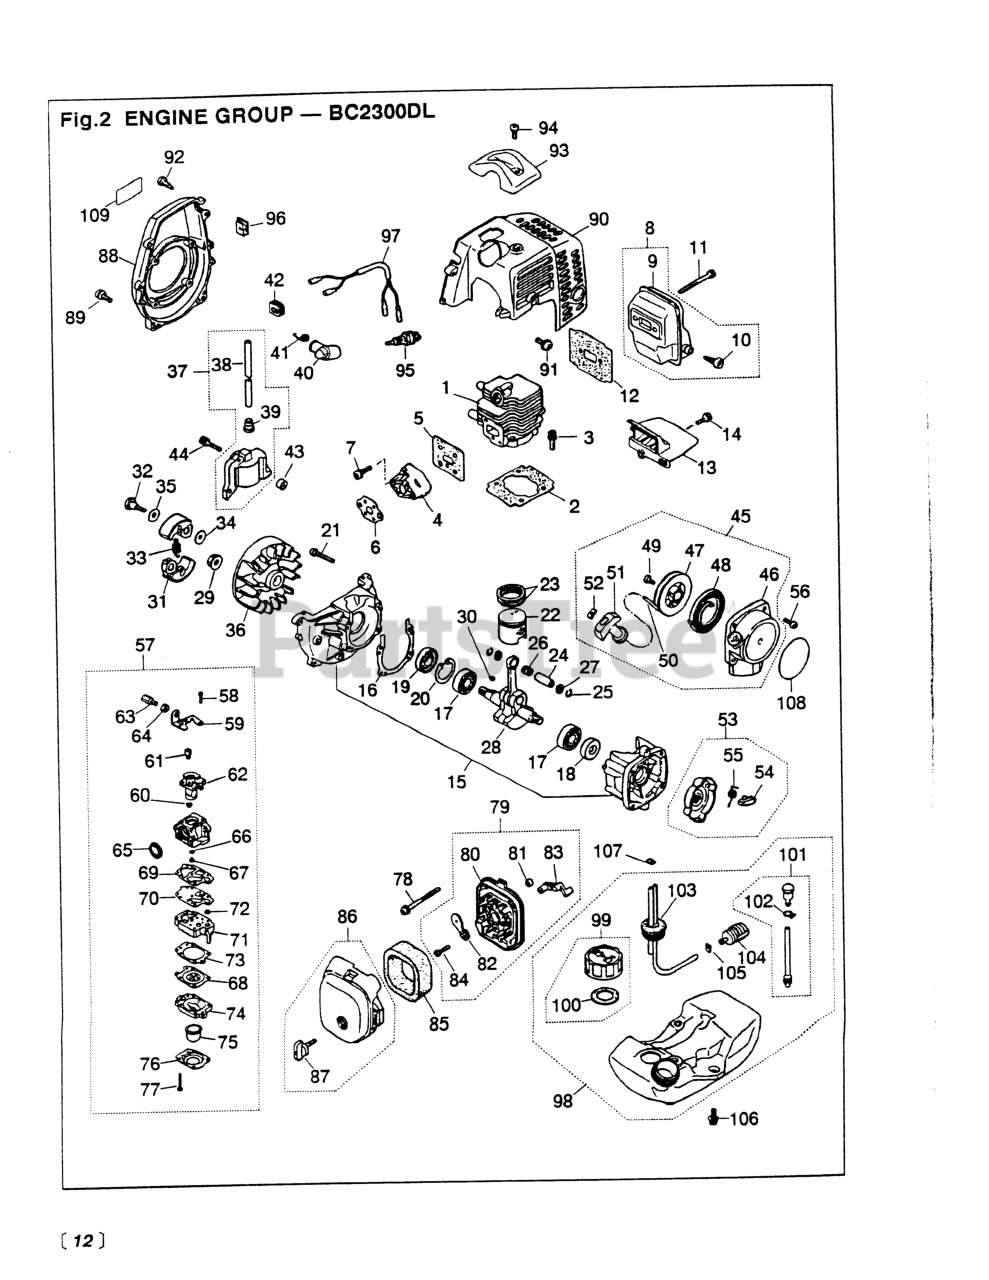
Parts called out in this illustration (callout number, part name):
1	CYLINDER
3	BOLT, M5 X 22
7	SCREW, M5X20 (RPLS.1400-75510)
9	MUFFLER ASSY (USE 5913-15100)
10	ARRESTER (RPLS 5850-15140)
11	BOLT, M5 x 50
12	GASKET, MUFFLER
14	SCREW, M4 X 16
15	CRANKCASE
17	BEARING
18	SEAL, OIL (RPLS 1100-21210)
19	SEAL, OIL (RPLS 1140-21220)
20	RING, SNAP, M28 x 1.2
21	SCREW, M5 x 30(RPLS 0263-00530
24	PIN, PISTON 5x8x26
25	RING, SNAP (RPLS 1101-41320)
27	WASHER
30	KEY
32	BOLT
34	WASHER, FLAT (USE 182303)
38	CORD
39	CAP
41	SPRING
42	GROMMET
44	BOLT
45	RECOIL ASSEMBLY
46	CASE
47	REEL
48	SPRING, SPIRAL
49	SCREW (RPLS -75150)
51	KNOB
52	PLATE, STOPPER
53	PULLEY ASSY (RPLS -75210)
54	RATCHET (RPLS 1850-75220)
55	SPRING, RETURN
56	SCREW, M4 X 16
57	CARBURETOR (RPLS -81001)
58	SCREW
60	RING
61	SWIVEL
63	SCREW, CABLE ADJUSTER
64	NUT, CABLE ADJUSTER
65	RING, PACKING
66	RING, O
67	JET
68	DIAPHRAGM (USE 4810-81260)
69	GASKET, PUMP
70	DIAPHRAGM
71	BODY, PUMP
73	GASKET, DIAPHRAGM
74	BODY, PURGE
75	PUMP, PRIMING
76	COVER, PUMP
77	SCREW
78	SCREW, M5 X 55
80	BODY
81	SLEEVE
83	LEVER, CHOKE
84	SCREW (REPLACES 50030272)
85	ELEMENT
89	SCREW, M5X20 (RPLS.1400-75510)
91	SCREW, M5 x 12
92	SCREW, HOUSING
93	GUARD, PLUG
94	SCREW, M5 X 12
97	CORD COMP (RPLS -73200)
100	PACKING
102	CLIP
103	PIPE COMPLETE
104	FILTER ASSY
105	CLIP (REPLACES 2841-31280)
106	SCREW
107	CLIP
109	LABEL, FAN COVER
